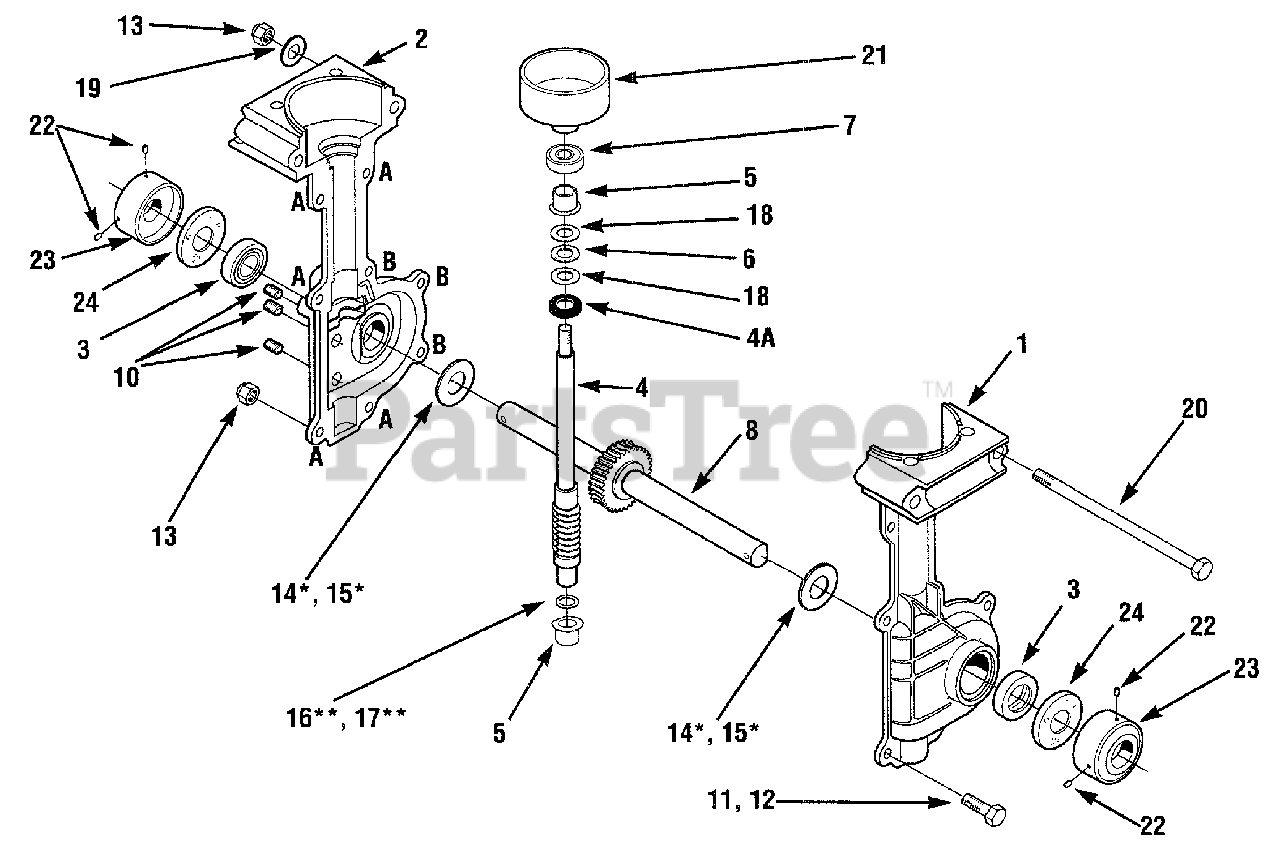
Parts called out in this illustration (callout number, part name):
1	Transmission Case, with pressed-in bushing, left-side
2	Transmission Case, with pressed-in bushing, right-side
3	Oil Seal
4	Shaft, worm-input
4A	Oil Seal, input
5	Bearing, input
6	Bearing, thrust
7	Ball Bearing
8	Shaft Assembly
10	Plug, 1/8"
11	Screw, 1/4"-20 x 7/8"
12	Screw, 1/4"-20 x 1"
13	Lock Nut, Nyloc, 1/4"-20
14	Thrust Washer, output (.050")
15	Thrust washer, output (.040")
16	Thrust Washer, input (.020")
17	Thrust Washer, input (.035")
18	Thrust washer
19	Flat Washer, 1/4"
20	Screw, Hex Hd., 1/4"-20 x 5"
21	Clutch Drum and Hub
22	Set Screw, 1/4"-28 x 3/8"
23	Dust Cover
24	Felt washer
